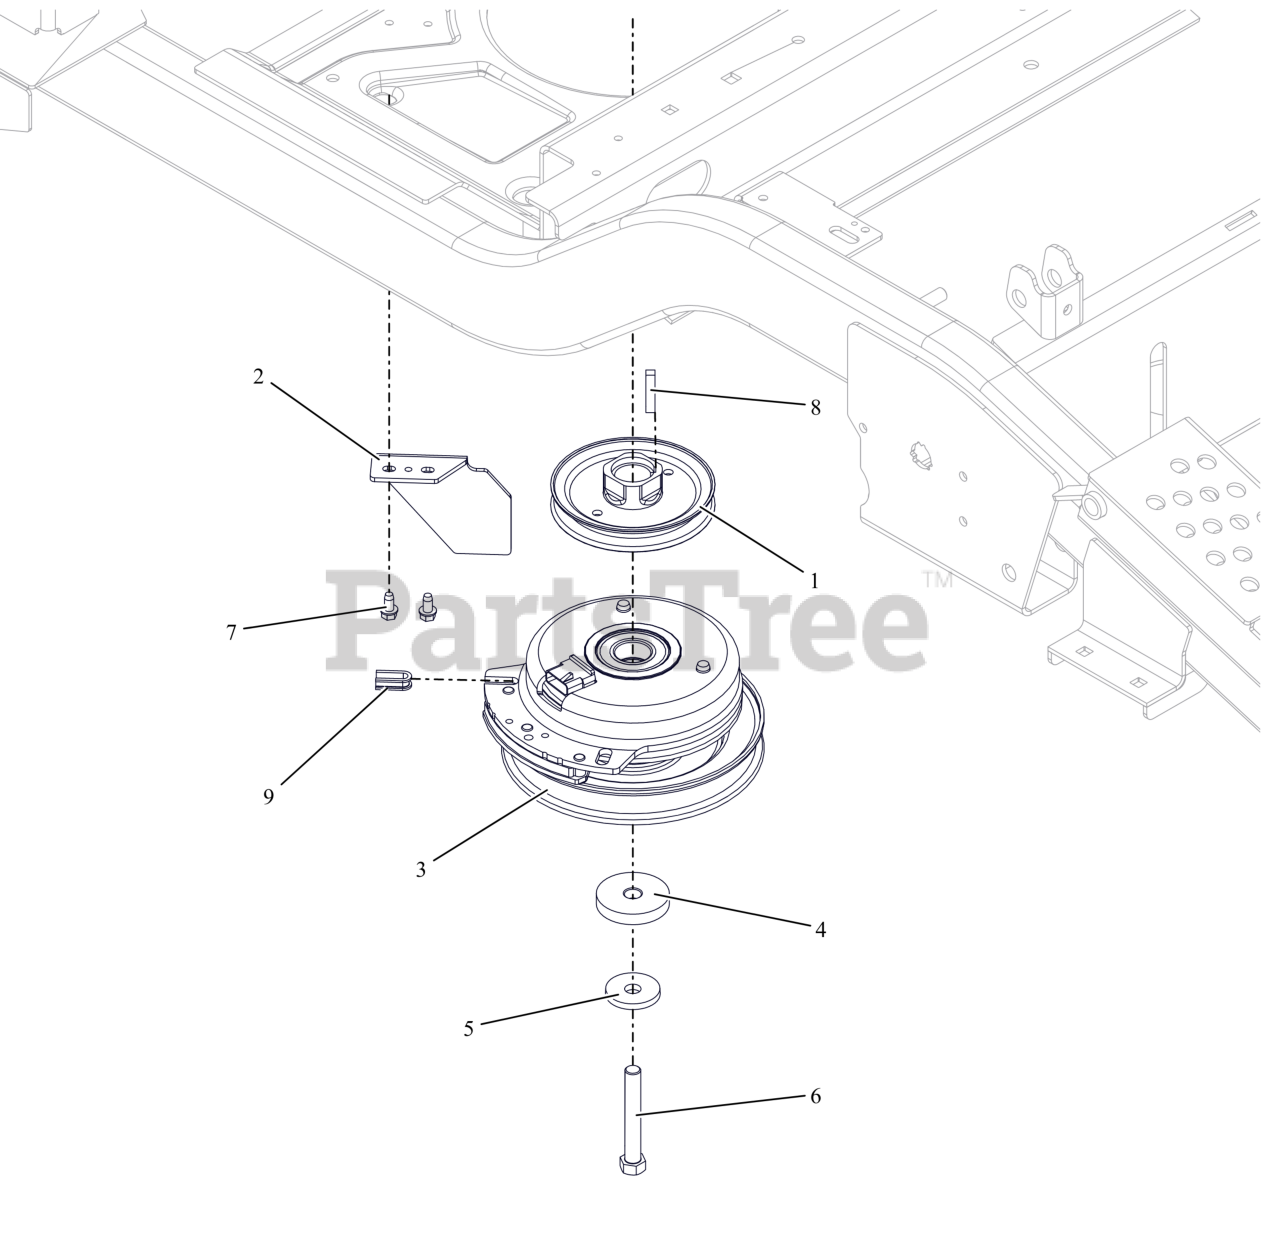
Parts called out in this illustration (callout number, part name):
1	PULLEY, 4.50 OD X 1.003 ENGINE
2	BRKT, CLUTCH
3	CLUTCH, WARNER 1.00 HD,PTZ
4	SPACER, .474/.459X2.00X.350
5	WASHER, 7/16" SPRING DISK
6	BLT, HEX .44-20X3.00 G8 ZCC NT
7	SCR-TAP .25-20X.50 HWH ZCC
8	KEY-SQ .25 X 1.25 X .25 SAE
9	BSHG, CLUTCH
